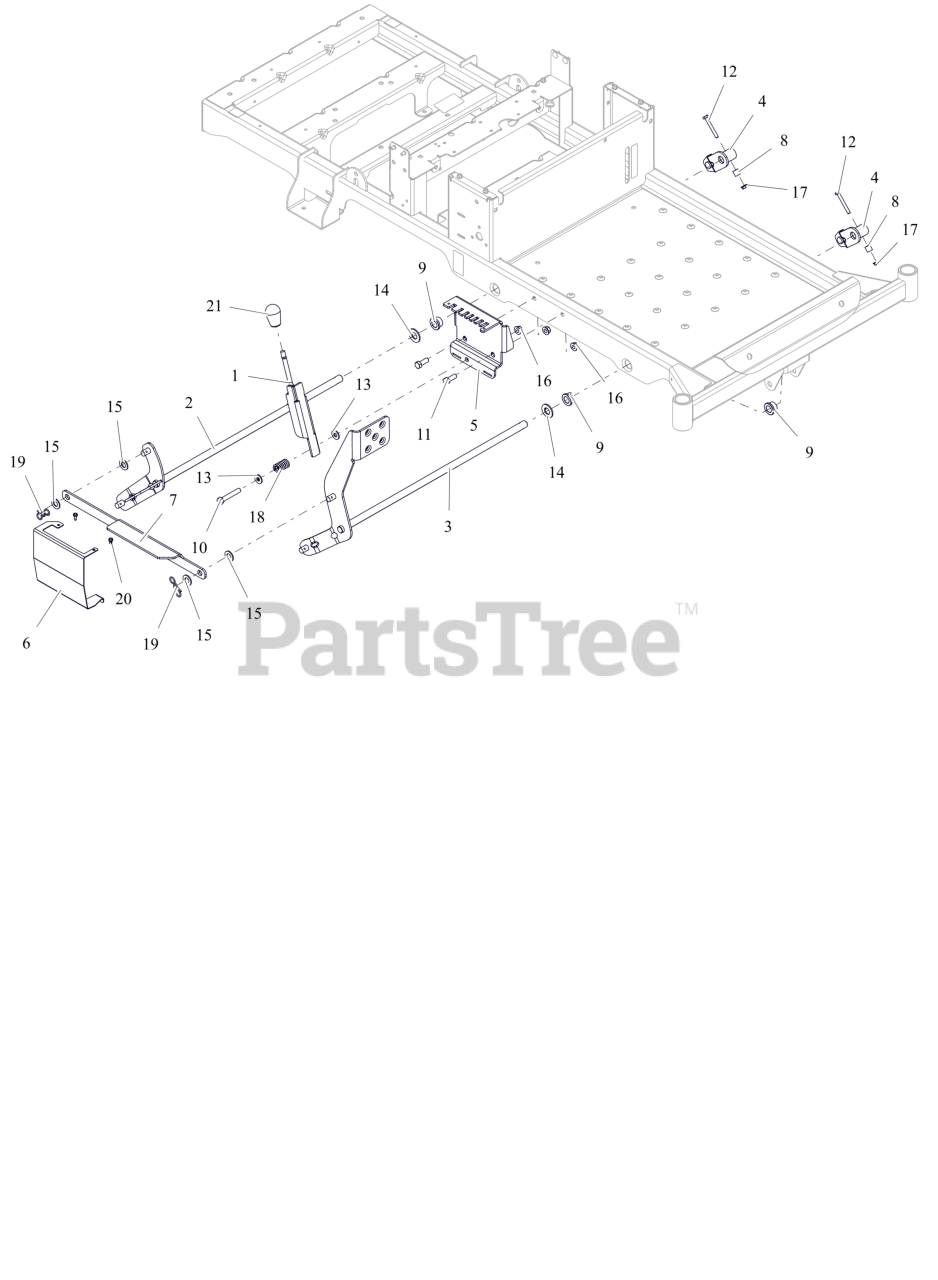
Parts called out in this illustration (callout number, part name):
1	WLDMT, HEIGHT OF CUT (ORANGE)
2	WLDMT, REAR DECK LIFT (ORANGE)
3	WLDMT, FOOTPEDAL (ORANGE)
4	WLDMT, DECK LIFT ARM (ORANGE)
5	PLATE, HEIGHT (ORANGE)
6	GUARD, DECK HOC (ORANGE)
7	LINK, LIFT /HOC (ORANGE)
8	BSHG-SLV .265X.500X.500
9	BSHG-FLG .629X.879X.469X1.250
10	BLT,HEX .38-16X2.25 G5 ZCC
11	BLT,HEX .38-16X1.00 G5 ZCC
12	BLT, HEX .25-20X2.00 G5 ZCC
13	WSHR,FLT .375X.875X.083 ZCC
14	WSHR, FLT .656X1.313X.095 ZCC
15	WSHR-FL-NYL .518X1.000X.080
16	NUT-LK-CTR-FLG .375-16 GF ZCC
17	NUT-LK-CTR-FLG .25-20 ZC120
18	SPRG, COMPRESSION
19	PIN, BOWTIE .091X1.875 ZCC
20	SCR,TAP #10-24X.50 HWH TR ZCC
21	KNOB,SOFT TEARDROP,PUSH-ON BLK
